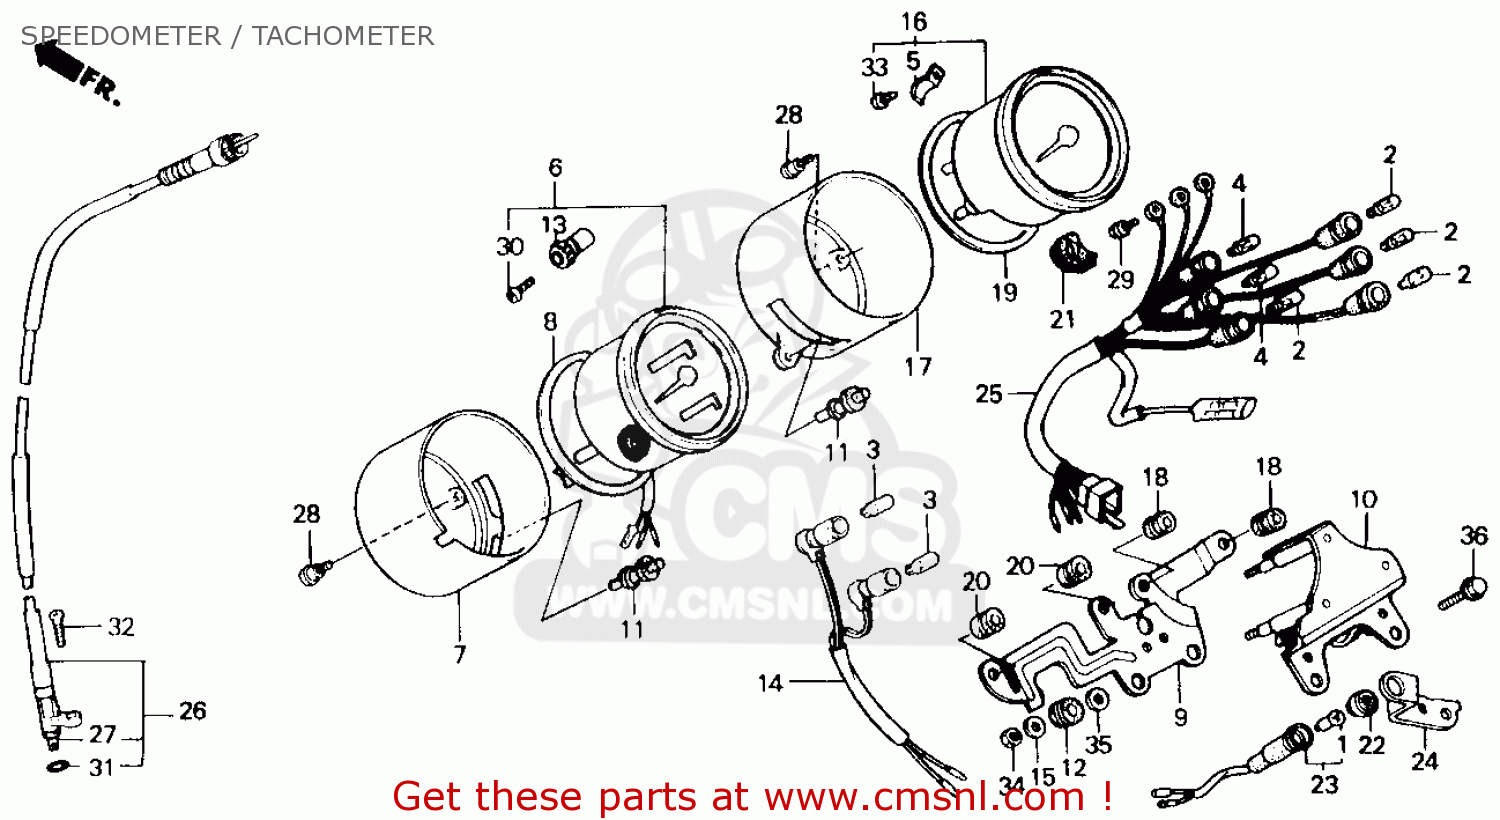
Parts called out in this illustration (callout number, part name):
1	BULB, DASH
2	BULB,WEDGE BASE,(
3	BULB,WEDGE BASE
4	BULB,WEDGE BASE (
5	CLAMP
6	SPEEDOMETER ASSY.
7	COVER,SPEEDOMETER
8	CUSHION,SPEEDOMET
9	BRACKET (A)
10	BRACKET ASSY.(B)
11	STOPPER,METER BRA
12	RUBBER,MOUNTING
13	KNOB
14	SOCKET COMP.
15	WASHER,PLAIN
16	TACHOMETER ASSY.
17	COVER,TACHOMETER
18	CUSHION,TACHOMETE
19	CUSHION,TACHOMETE
20	CUSHION,SPEEDOMET
21	GROMMET,TACHOMETE
22	LENS COMP.,SIDE S
23	SOCKET COMP.,SIDE
24	STAY,SIDE STAND W
25	CORD COMP.
26	CABLE ASSY.,SPEED
27	CABLE,INNER
28	SCREW,TRUSS,4X12
29	SCREW-WASHER,3X10
30	SCREW,PAN,2X6
31	ORING,6.8X1.9
32	SCREW,OVAL,5X16
33	SCREW,4X12
34	NUT,HEX.,6MM
35	WASHER,PLAIN,8MM
36	BOLT FLANGE 8X16
